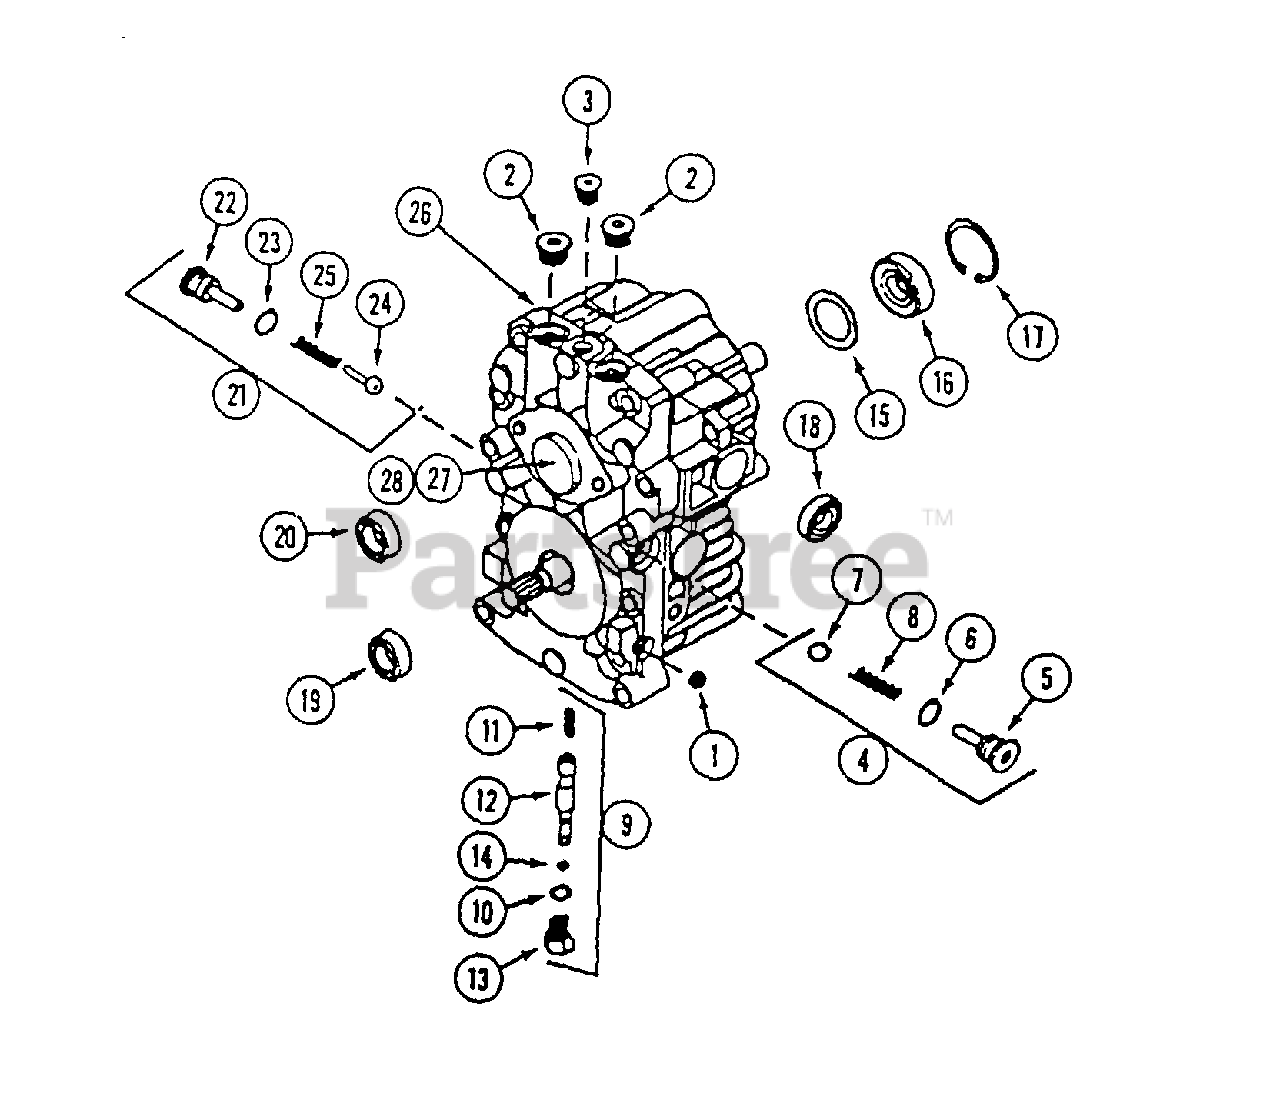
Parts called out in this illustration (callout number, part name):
1	PLUG - pipe
2	PLUG - 9/16" - 18
3	PLUG - 7/16" - 20
4	KIT - check valve (with check ball) top
5	PLUG - check valve
6	"O" RING - .078" x .468"
7	BALL - check
8	SPRING
9	KIT - by pass
10	"O" RING - .072 x .351
11	SPRING
12	SPOOL - by pass
13	PLUG - by pass
14	"O" RING
15	SPACER
16	SEAL - lip
17	RING - retaining
18	SEAL - lip
19	SEAL - lip
20	SEAL - lip
21	KIT - check valve (with poppet) bottom
22	PLUG - check valve
23	"O" RING - .078" x .468"
24	POPPET - check
25	SPRING
26	GASKET - body
27	KIT - charge pump
28	O-RING - charge pump cover
